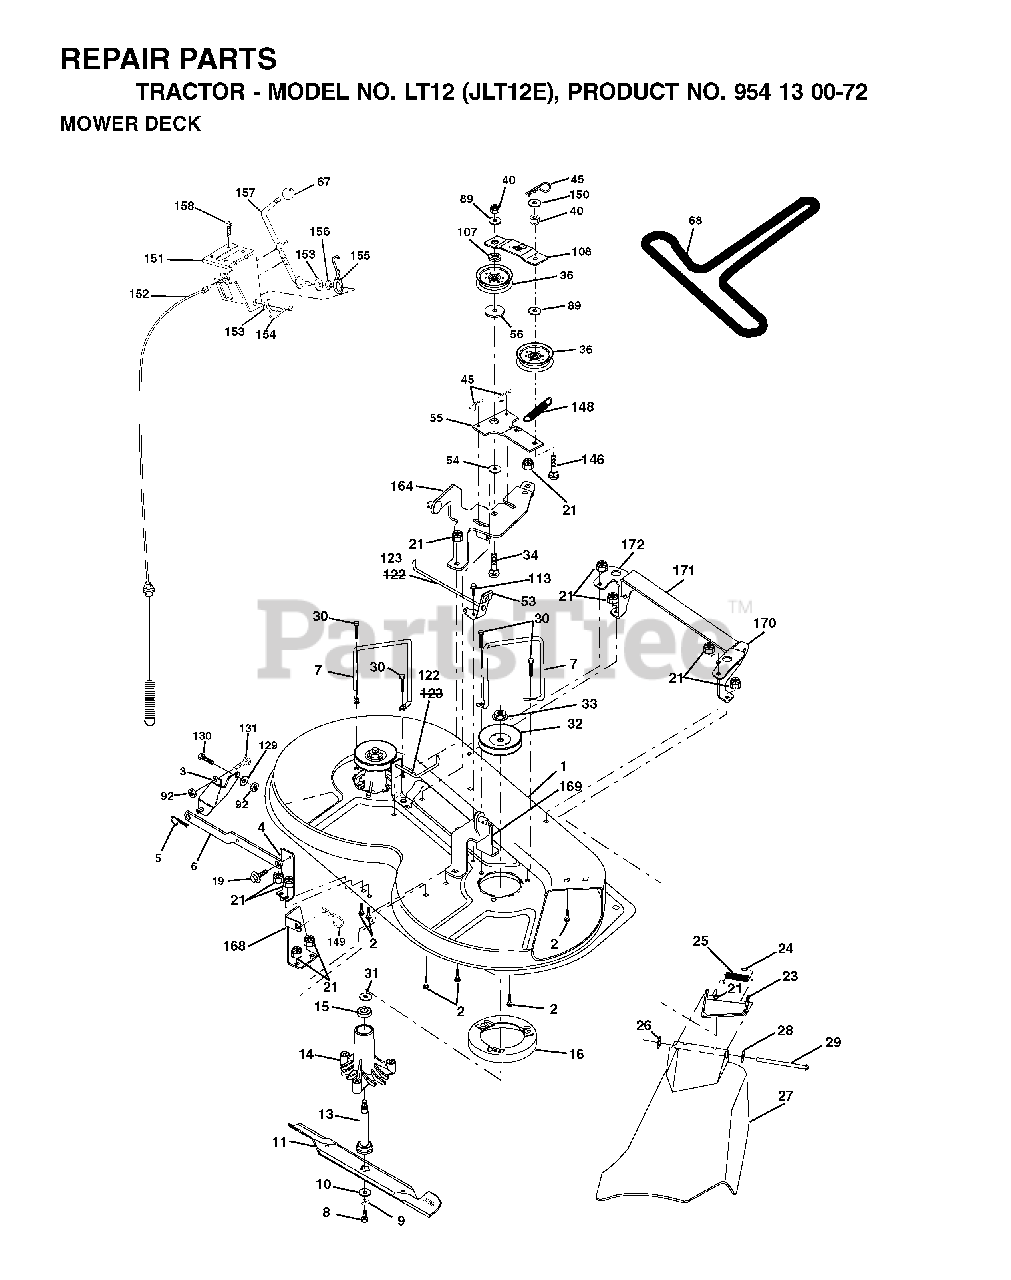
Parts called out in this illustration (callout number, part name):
2	BOLT
3	BRKT ASM SWAY BAR
5	RETAINER-SPRNG RB
6	BAR SWAY DECK
7	KEEPER LH
8	BLADE BOLT
9	LOCKWASHER
10	WASHER.BLADE
11	BLADE, HI-LIFT 36" PREMIUM
13	SHAFT ASM VENT
14	HSG MANDREL
16	STRIPPER, MWR ROUND
19	BOLT SHD 5/16-18
21	LOCKNUT
23	BRACKET ASM DEFLECTOR
24	CAP-SLEEVE LT
25	SPRING TORSION
26	NUT PUSH M
28	WASHER
29	HINGE ROD
30	SCREW, WASHER HEAD
31	WASHER
32	PULLEY, MANDREL
33	NUT, FLG TOPLOCK 9/16"
34	BOLT
36	FLAT IDLER PULLEY
40	LOCKNUT
45	RETAINER M
53	BRAKE ASSEMBLY
54	HARDENED WASHER
55	IDLER ARM
56	SPACER.RETAINER.MOWER
67	KNOB T (3/8 HOLE)
68	V-BELT.MOWER.
89	WASHER GT
92	NUT
107	SPACER.IDLER.ARM
108	STIFFENER.IDLER.ARM
129	WASHER
131	BOLT D
146	BOLT, CARRIAGE IDLER
148	IDLER RETURN SPRING
149	SPRING.RETAINER.YELLOW.ZINC
150	WASHER PM
151	BRACKET, CLUTCH CABLE
153	WASHER FLAT 3/8"
154	SPRING RETAINER
155	SPRING RETENTION LEVER
156	SPACER CLUTCH CABLE
157	ROD CLUTCH CABLE 3/8"
158	SCREW
171	BRACE
